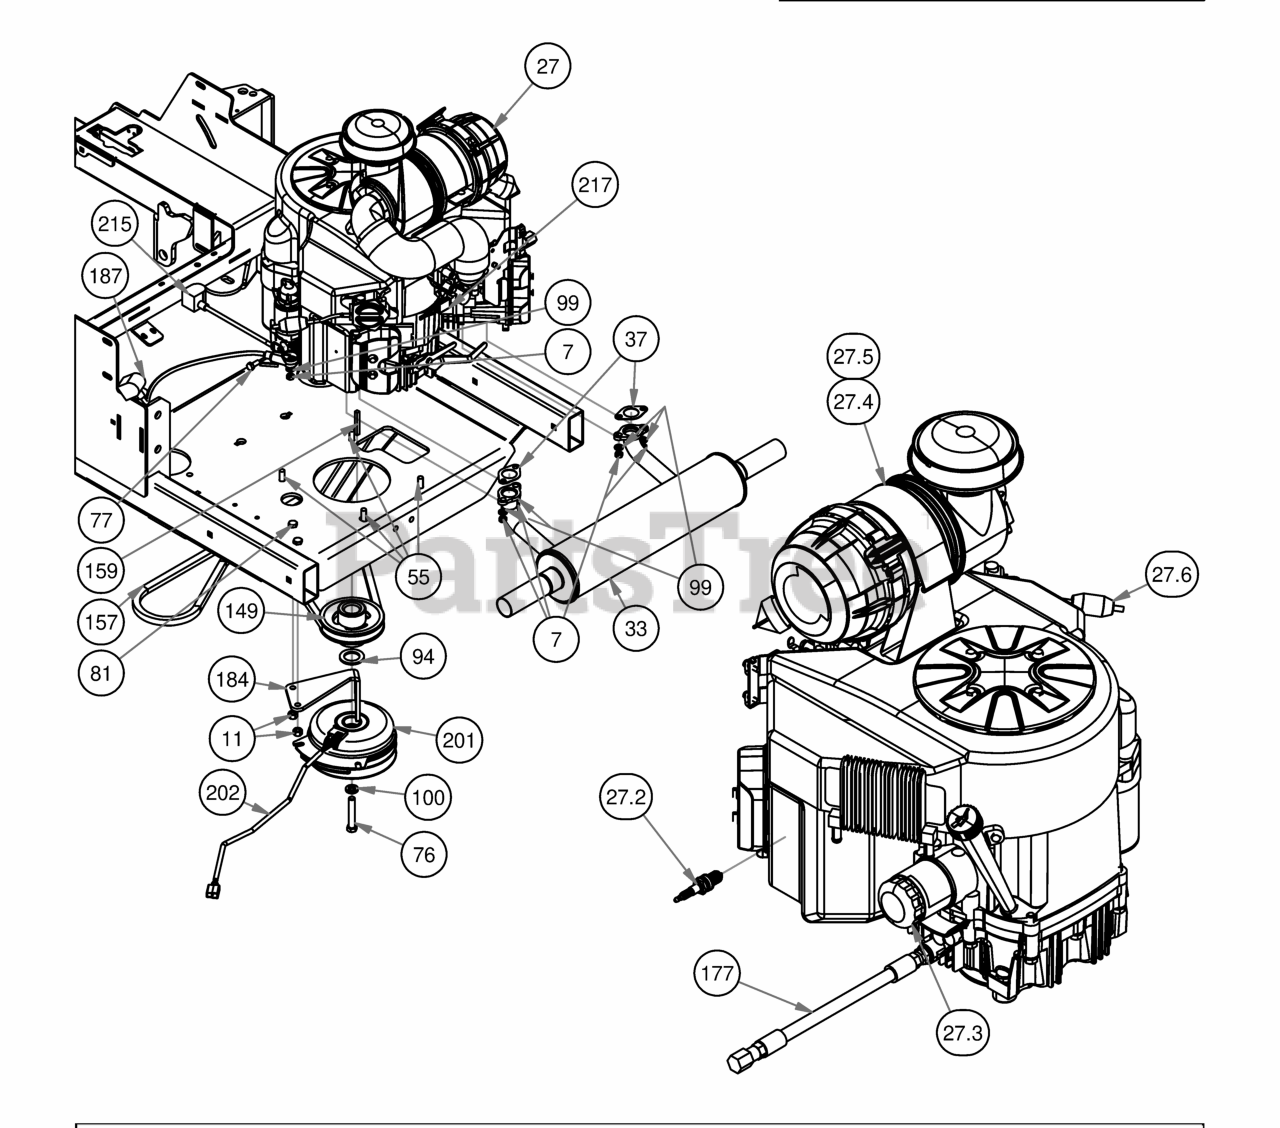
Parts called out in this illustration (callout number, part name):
7	M8-1.25 Zinc Nut
11	3/8" Hex Nut
27	Kawasaki FX850 Engine
27.2	Spark Plug - Kawasaki
27.3	Oil Filter
27.4	Canister Air Filter- Inner
27.5	Canister Air Filter- Outer
27.6	Universal Inline Fuel Filter
33	2019 Rebel/Rogue Kawasaki 850 Muffler
37	Exhaust Gasket
55	3/8 x 1 1/8 bolt
76	7/16" x 2 1/2" Hex Bolt
77	M8x1.20x20MM Hex head bolt
81	3/8" x 1" Hex Bolt
94	1 1/8" Flat Spacer
99	5/16" Lock Washer
100	7/16" Lock Washer
149	4 3/4 Motor Pulley
157	2019 Rogue Pump Belt 68"
159	1/4 x 2 Square key Stock
177	Kawasaki Oil Drain
184	PTO Engager Holder
187	24" Red Battery Cable
201	Clutch Assembly
202	Clutch Pigtail
203	2019 Veritical Suspension Frame
215	Starter Cable
217	Kawasaki Harness Adapter
